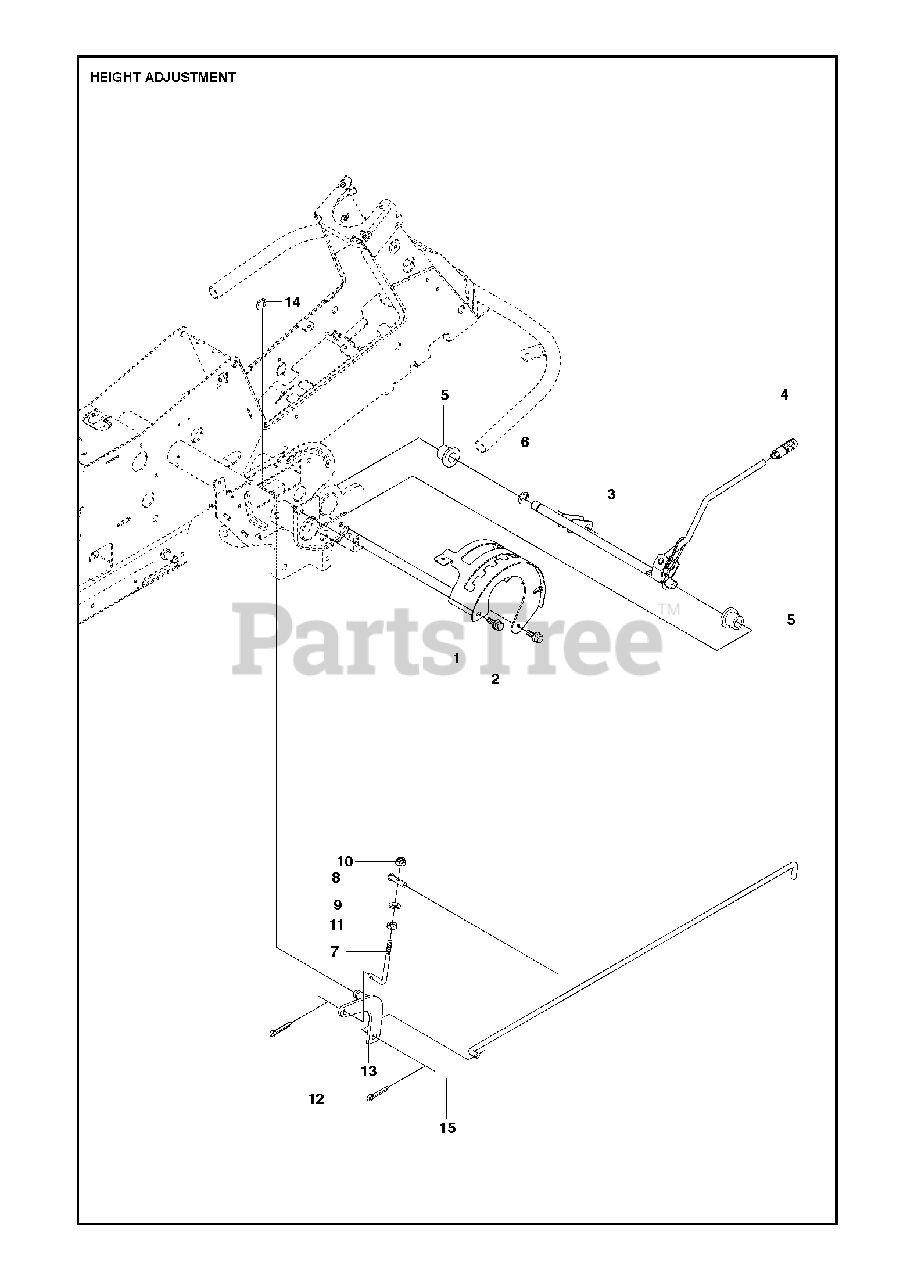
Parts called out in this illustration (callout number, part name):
4	GEAR STICK KNOB
5	BUSHING
9	WASHER
10	LOCKNUT M8
11	NUT
12	SPLIT PIN
15	CONNECTION ROD
